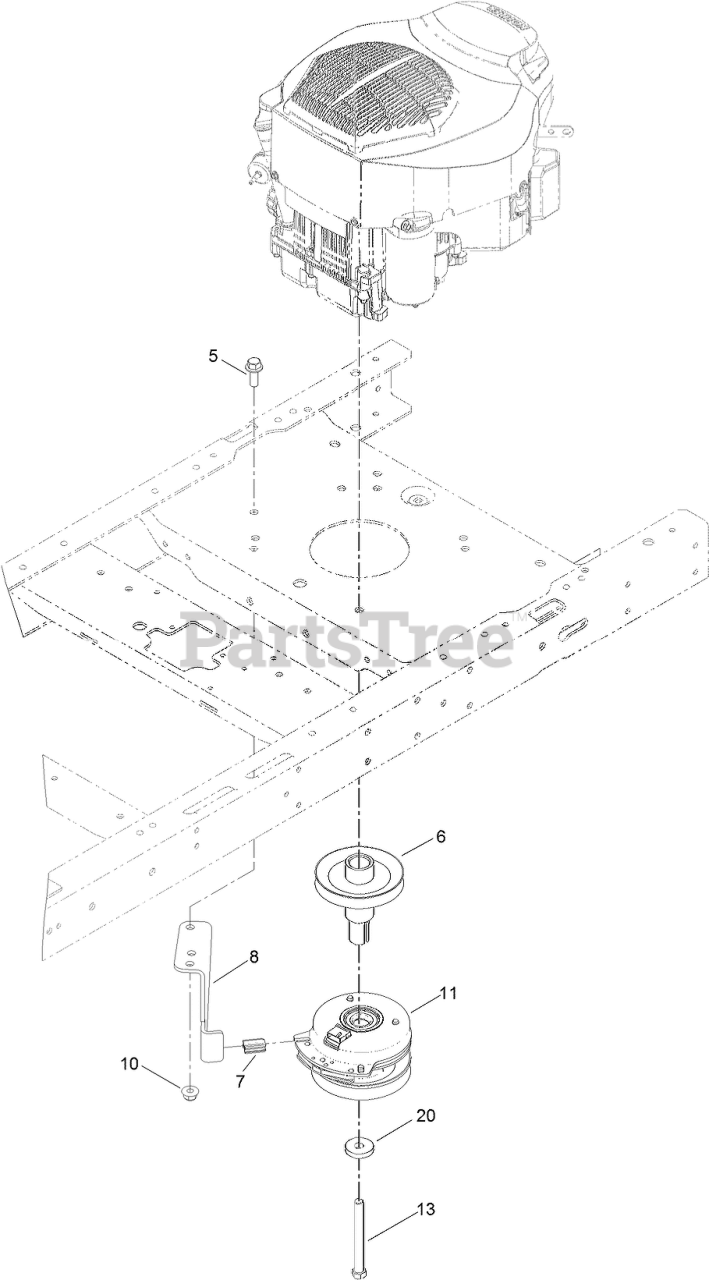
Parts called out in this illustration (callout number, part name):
5	SCREW-HHF
6	PULLEY-ENGINE
7	ISOLATOR-CLUTCH
8	STOP-CLUTCH
10	NUT-HF, NI
11	CLUTCH-PTO
13	SCREW-HH
20	WASHER
